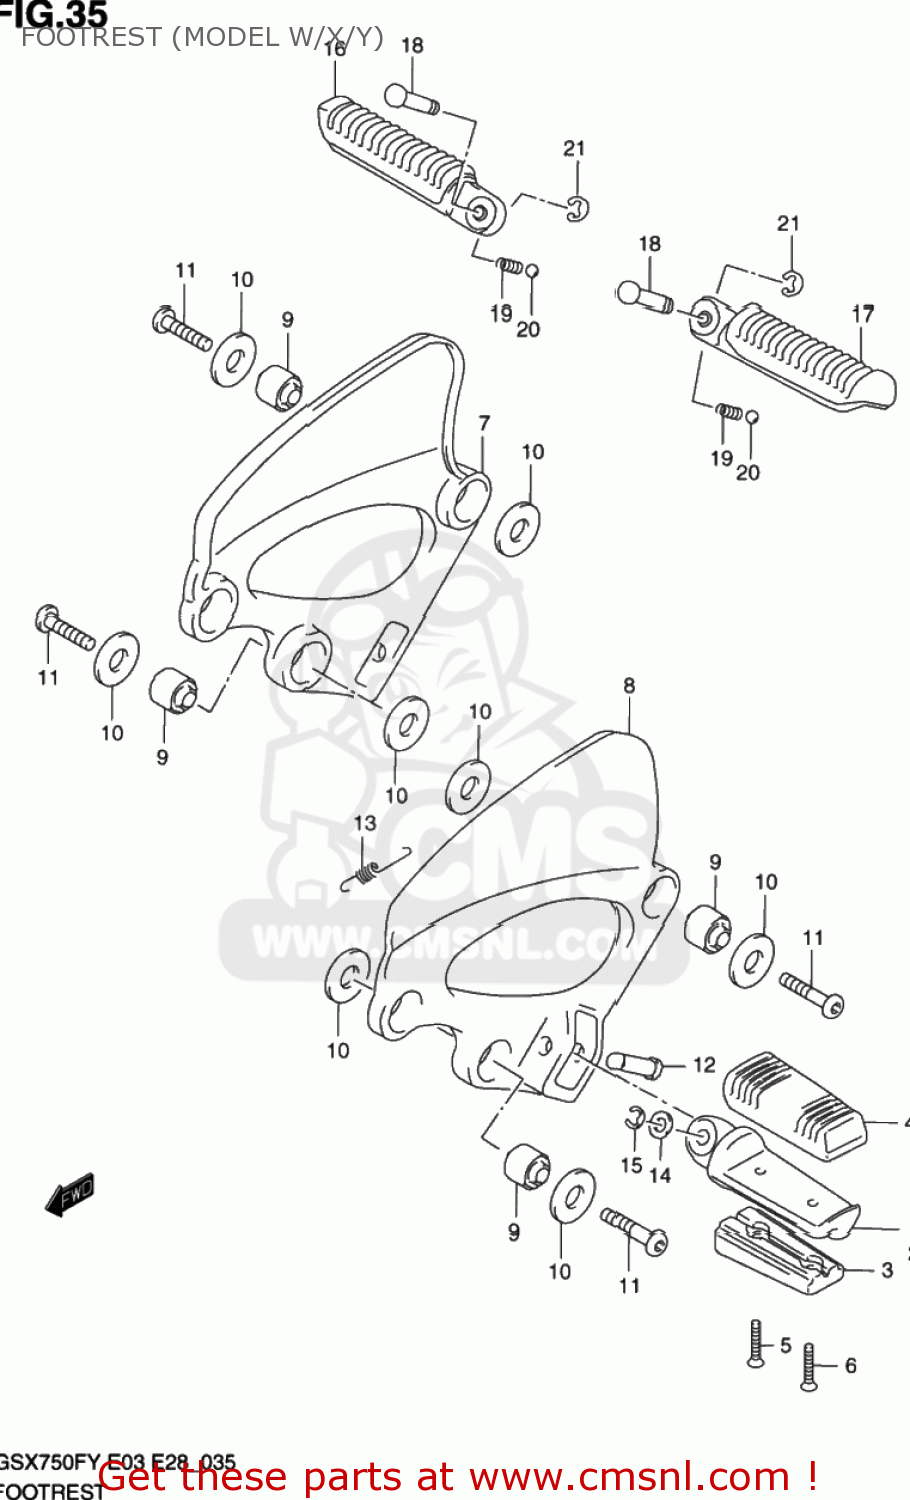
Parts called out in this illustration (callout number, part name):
1	BAR,FR FOOTREST,R
2	BAR,FR FOOTREST,L
3	BAR,FR FOOTREST NO.2
4	RUBBER,FR FOOTREST
5	SCREW, INNER
6	SCREW
7	HOLDER,FR FOOTREST,R
8	HOLDER,FR FOOTREST,L
9	BUSH(12X20X16)
10	WASHER(12.6X24X1.9)
11	BOLT L:30
12	PIN(8X33.2)
13	SPRING
14	WASHER
15	E.RING
16	BAR,PILLION FOOTREST,R
17	BAR,PILLION FOOTREST,L
18	PIN
19	SPRING
20	BALL
21	E.RING
